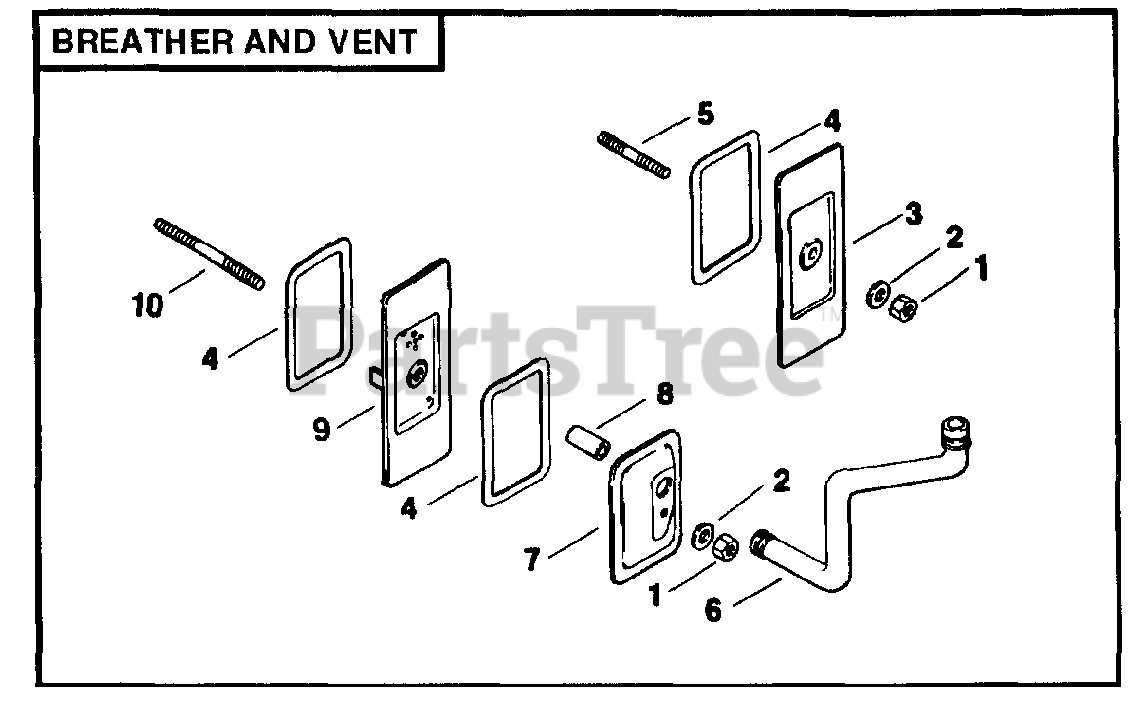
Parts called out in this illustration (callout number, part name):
1	NUT
2	WASHER
5	STUD
8	SEAL BREATHER
9	BREATHER ASSY
10	STUD
